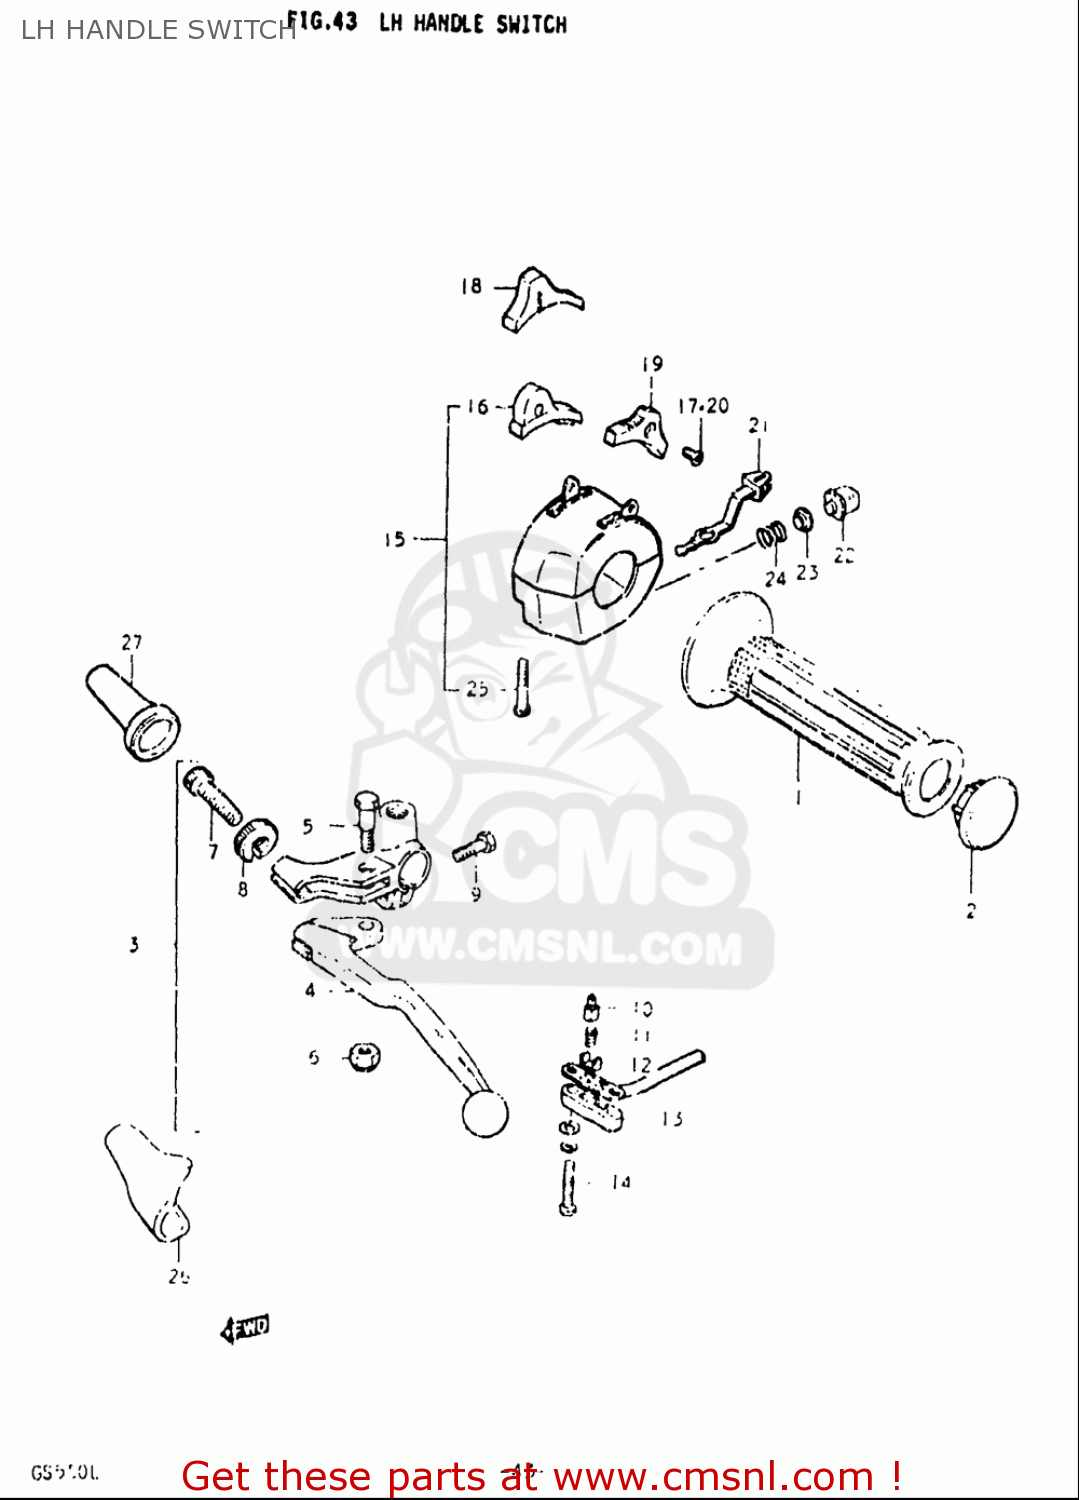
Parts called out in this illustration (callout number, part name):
1	GRIP,L
2	CAP,GRIP END
3	LEVER ASSY,CLUTCH
4	LEVER,CLUTCH
5	BOLT,LEVER PIVOT
6	NUT 6MM
7	ADJUSTER,CABLE
8	NUT,CABLE ADJUSTER
9	BOLT
10	CONTACT,SWITCH
11	CONTACT,SWITCH
12	CONTACT,SWITCH
13	COVER,FR BK TERMINAL BASE
14	SCREW
15	SWITCH ASSY,HANDLE,L
16	KNOB,STOP
17	SCREW
18	KNOB,LIGHTING SWITCH
19	KNOB,DIMMER SWITCH
20	SCREW
21	KNOB,TURNSIGNAL
22	BUTTON,HORN
23	CONTACT
24	SPRING
25	SCREW
26	COVER,CLUTCH LEVER
27	BOOT,CLUTCH CABLE
